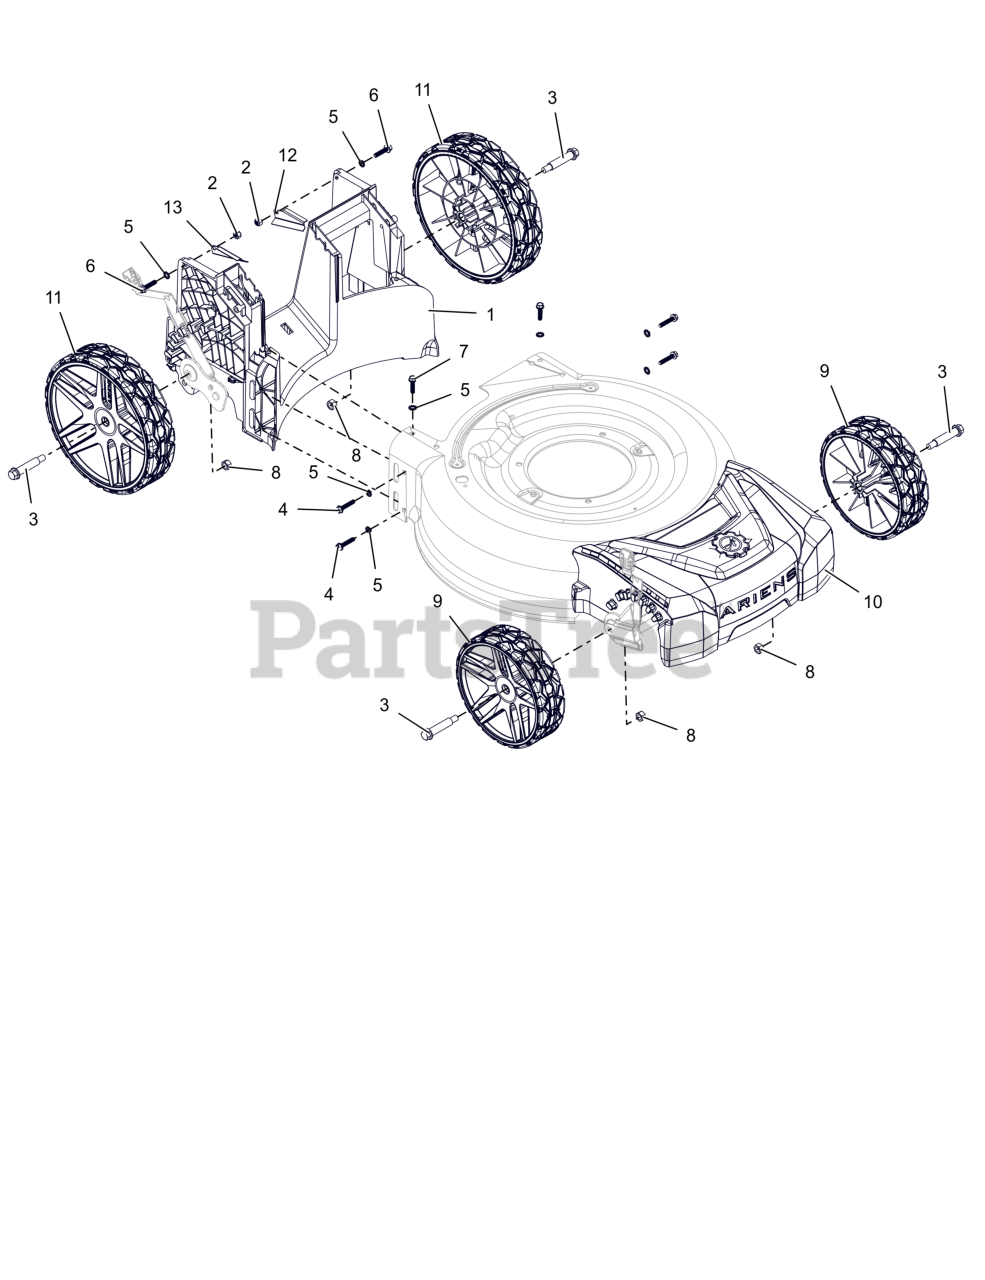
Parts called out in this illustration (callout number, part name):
1	ASM, REAR BAFFLE-FWD
2	NUT, NYLOC 1/4-20
3	BLT, SHLDR HWH .325X1.981X 3/8-16
4	SCR, HI-LO HWH 1/4-15 X 1.25
5	WSHR-LK-EXT, .256X.510X.028
6	BLT, HEX 1/4-20 X 1.125
7	SCR, HI-LO HWH 1/4-15 X 1.00
8	NUT-JAM .375-16 HIGH STRENGTH
9	WHEEL, 8" - GRAY
10	COVER, FRONT
11	WHEEL, 10" - GRAY
12	BRKT, LH DOWNWARD (BLACK)
13	BRKT, RH DOWNWARD (BLACK)
